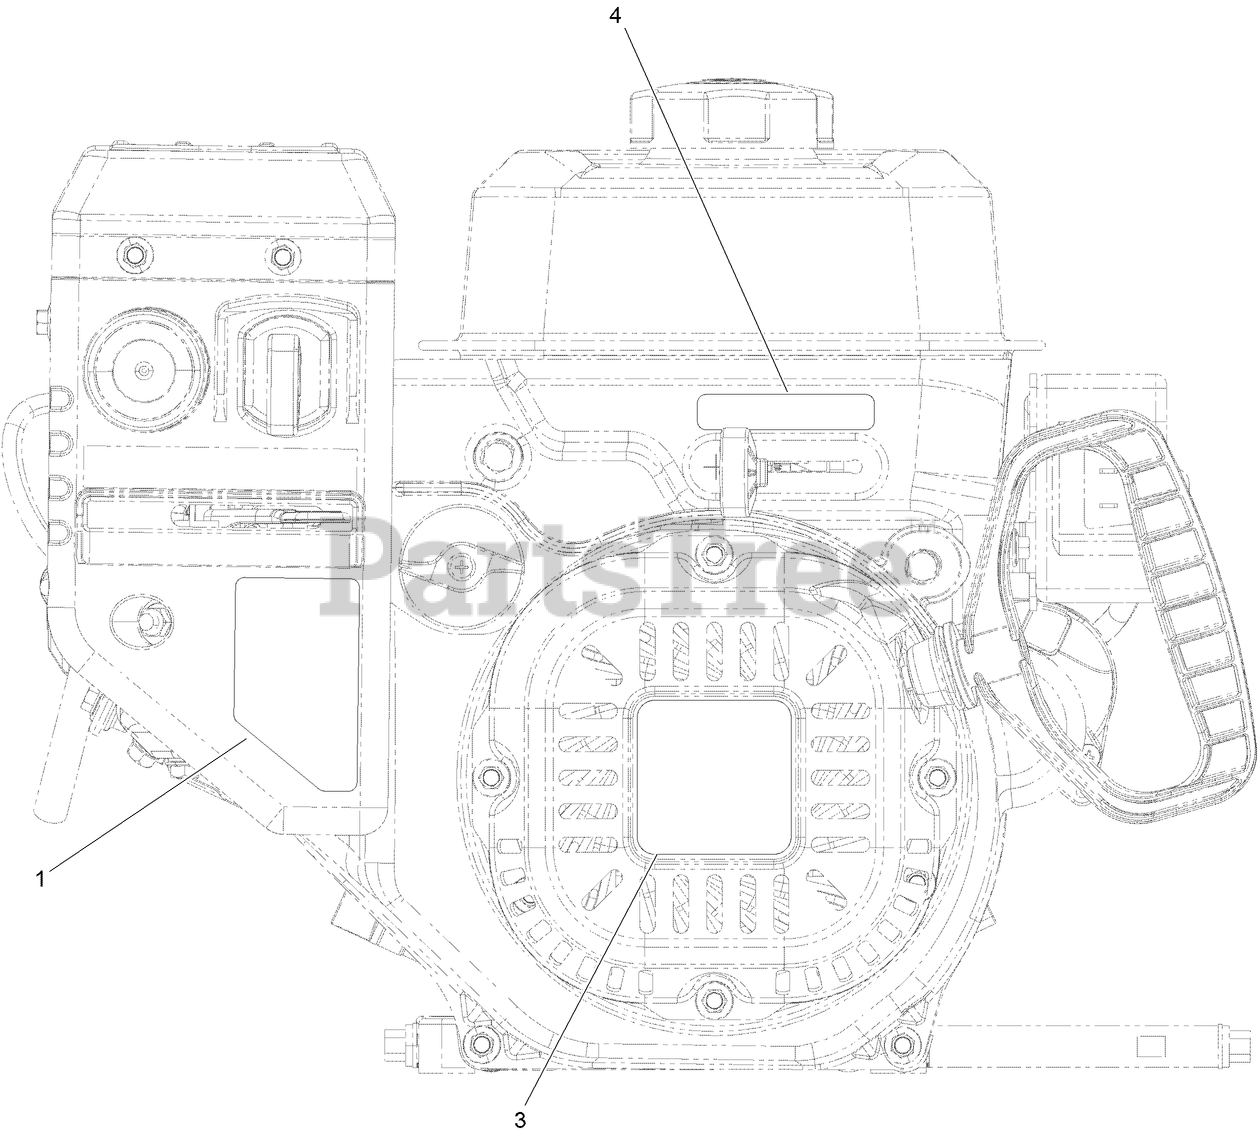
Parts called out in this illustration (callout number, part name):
1	DECAL-CONTROL, ENGINE
3	DECAL-RECOIL, G250
4	DECAL-THROTTLE
